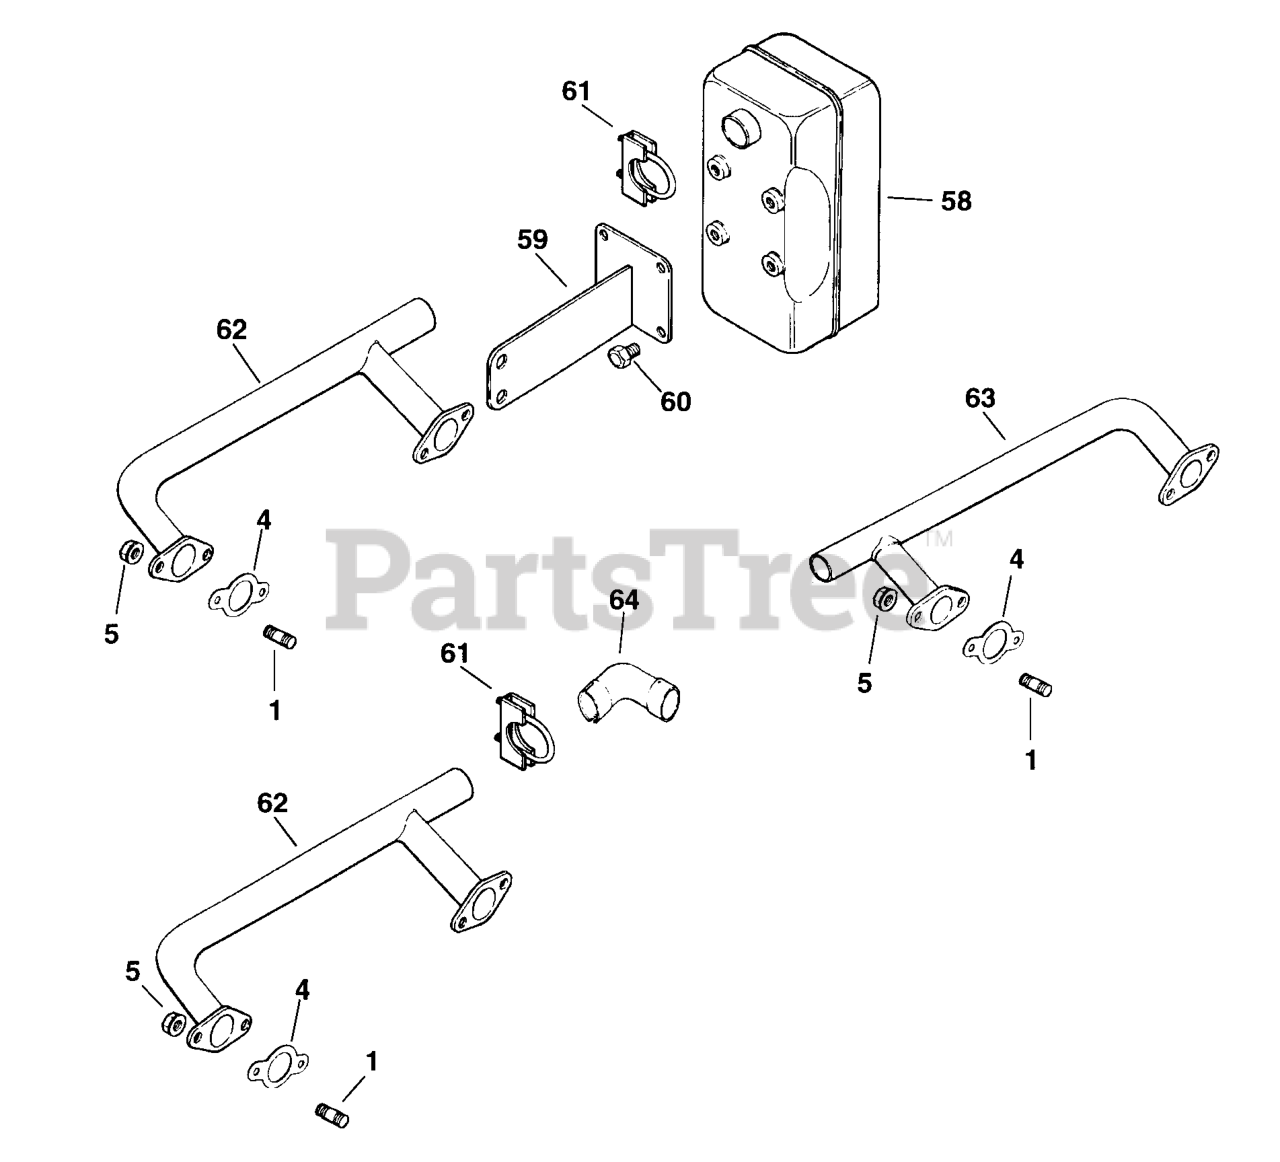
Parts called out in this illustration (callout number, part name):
1	Stud, Exhaust M8x1.25x33
4	Gasket, Exhaust
5	Nut, Hex. Flange M8x1.25
58	Muffler, Starter Side Outlet
59	Bracket, Muffler
60	Screw, Sems Hex. Cap 10-24x13/32"
61	Clamp, Muffler
62	Manifold, Exhaust - #1 Side
